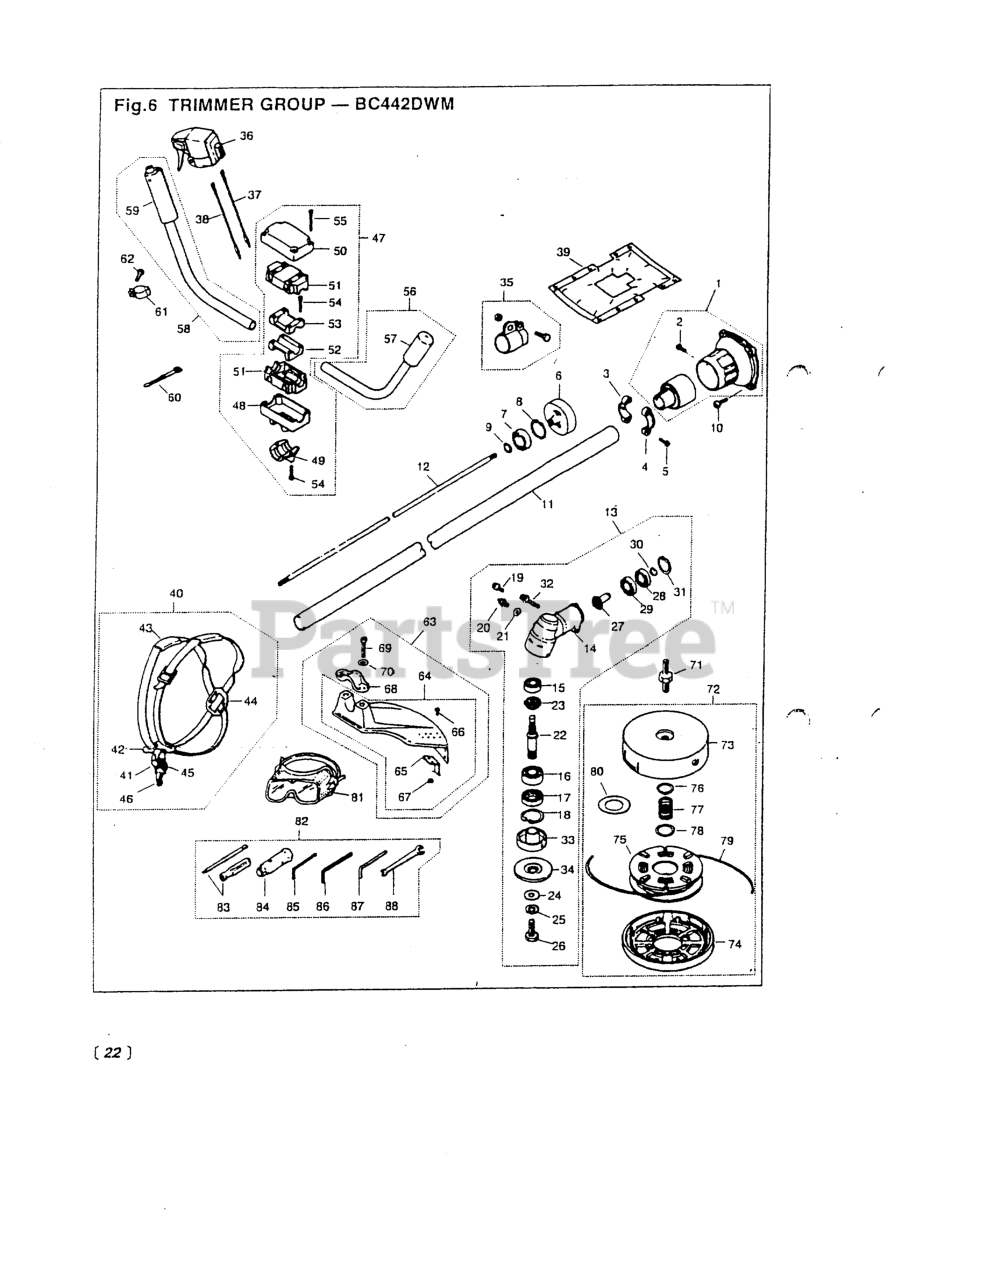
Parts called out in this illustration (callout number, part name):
1	HOUSING COMP.
2	SCREW, M6 x 10
4	CLAMP (B)
5	BOLT
6	DRUM, SPLINED
7	BEARING
8	RING, SNAP, M35 X 1.5
9	RING, SNAP, M15 X 1.0
10	BOLT, M6 X 20
12	SHAFT (USE 6340-12211)
13	GEARCASE ASSY (RPLS -13001)
14	GEARCASE (RPLS -13113)
15	BEARING (RPLS T3403-13510)
18	RING, SNAP, M35 X 1.5
19	BOLT, M5 X 10
20	FITTING, GREASE
21	WASHER, M6 X .8
22	SHAFT (RPLS -13211)
24	WASHER, M10 x 3.2
25	WASHER
26	BOLT (REPLACES 3130-13260)
28	BEARING
29	BEARING
31	RING, SNAP, M28 x 1.2
32	BOLT, M6 x 1.35
33	HOLDER (A) (RPLS -13240)
34	HOLDER (B)
35	HANGER COMPLETE
36	LEVER ASSEMBLY
37	CORD A (RED)
38	CORD (RPLS -14720)
43	PROTECTOR
49	CAP, LOWER
50	CAP, UPPER
51	ABSORBER
52	CLAMP (A)
53	CLAMP (B)
54	BOLT, M5 X 25
55	BOLT, M5 X 30
56	HANDLE COMPL, LEFT
58	HANDLE COMPL, RIGHT
59	GRIP
60	BAND
61	CLAMP
62	SCREW, M5 X 16
63	GUARD ASSY (RPLS 6231- )
65	BLADE
66	SCREW, M5 x 12
67	NUT
69	BOLT, M6 x 1.30
70	WASHER, M6 X 15
71	ARBOR, 10MM
72	6
74	COVER
76	PLATE, LARGE
78	PLATE, SMALL
79	CORD
80	SPACER
83	SCREWDRIVER
85	WRENCH (TOOL)
86	WRENCH (TOOL)
87	BAR
88	SPANNER, 8 X 10 (RPLS 2540- )
